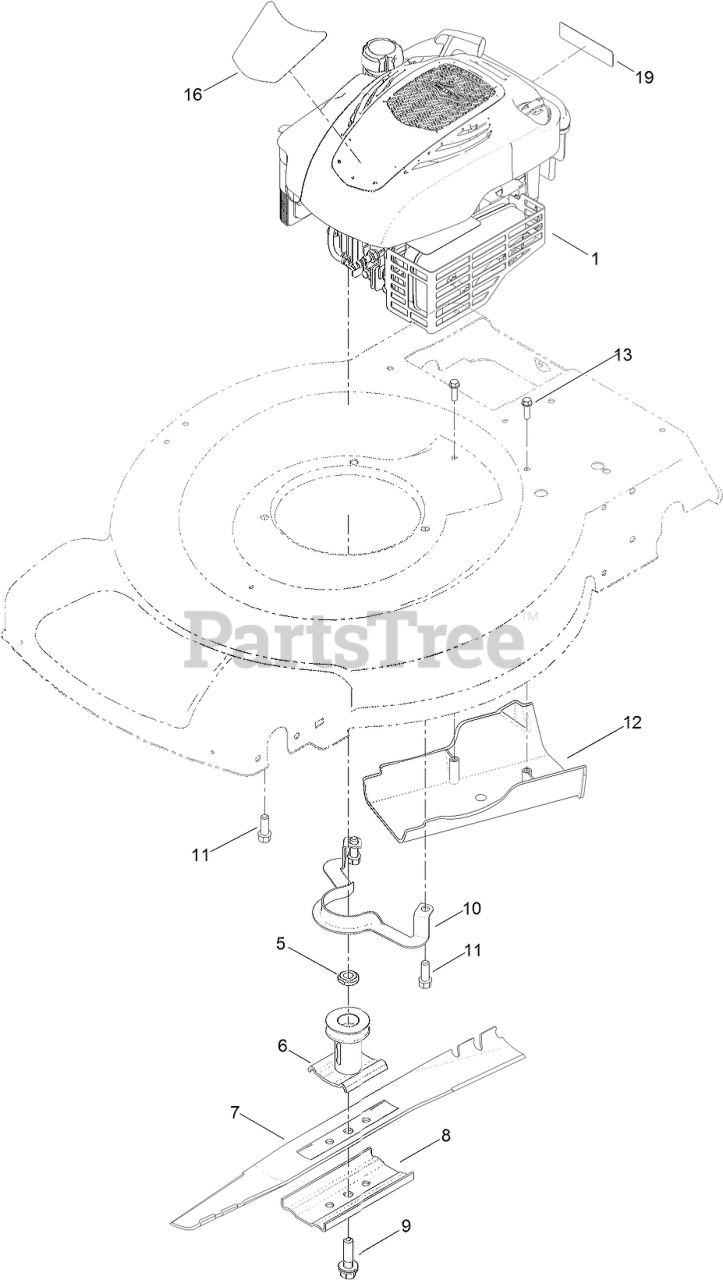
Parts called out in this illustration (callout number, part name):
5	Spacer-Driver
6	DRIVER-BLADE
7	BLADE-22 INCH
8	SUPPORT-BLADE
9	BOLT-BLADE
10	Guide-Belt
11	SCREW-TAPTITE
12	COVER-BELT
13	SCREW-HWH
16	DECAL-SHROUD
19	DECAL-ARRESTER, SPARK
